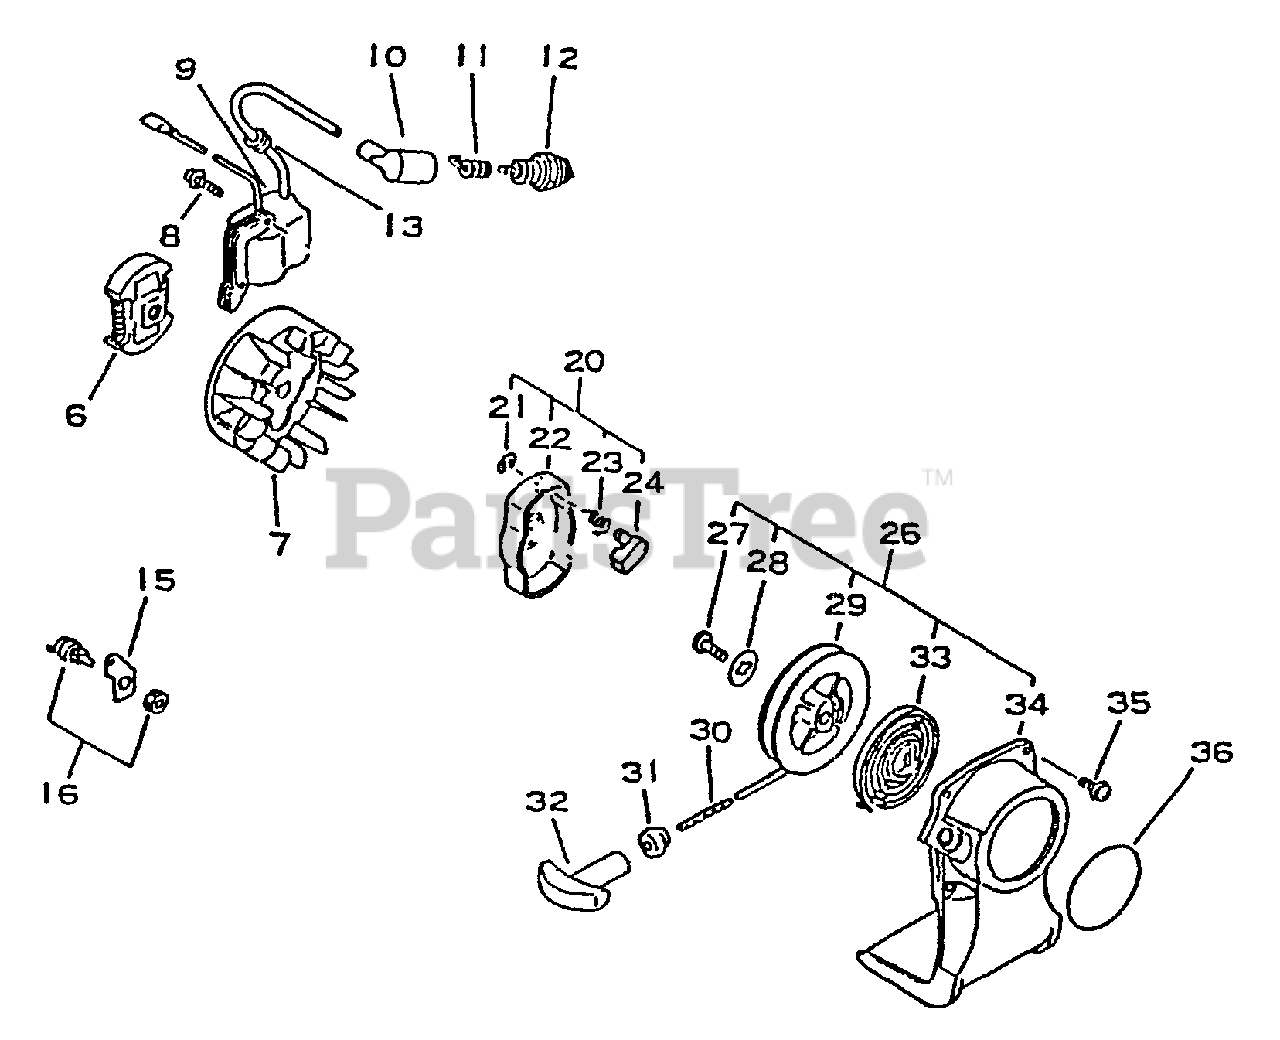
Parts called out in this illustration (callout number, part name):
6	CLUTCH ASSY
7	FLYWHEEL
8	SCREW - 4X22
9	COIL, IGNITION
10	CAP, SPARK PLUG
11	TERMINAL, SPARK PLUG CAP
12	SPARK PLUG -- BPM-7A
12	SPARK PLUG -- CJ-7Y
13	GROMMET
15	BRACKET, SWITCH
16	IGNITION SWITCH ASSY
20	STARTER PAWL ASSY
21	RING, RETAINING - 4
22	CATCHER, PAWL
23	SPRING, RETURN
24	PAWL, STARTER
26	STARTER ASSY - BLACK
28	WASHER
29	REEL, ROPE
30	ROPE, STARTER - 3X890
31	GUIDE, ROPE
32	GRIP, STARTER
33	SPRING, REWIND
34	CASE, STARTER - BLUE
35	SCREW - 4X16
36	LABEL - ECHO
C12	SPARK PLUG -- BPMR-7A
C12	SPARK PLUG -- RCJ-7Y
